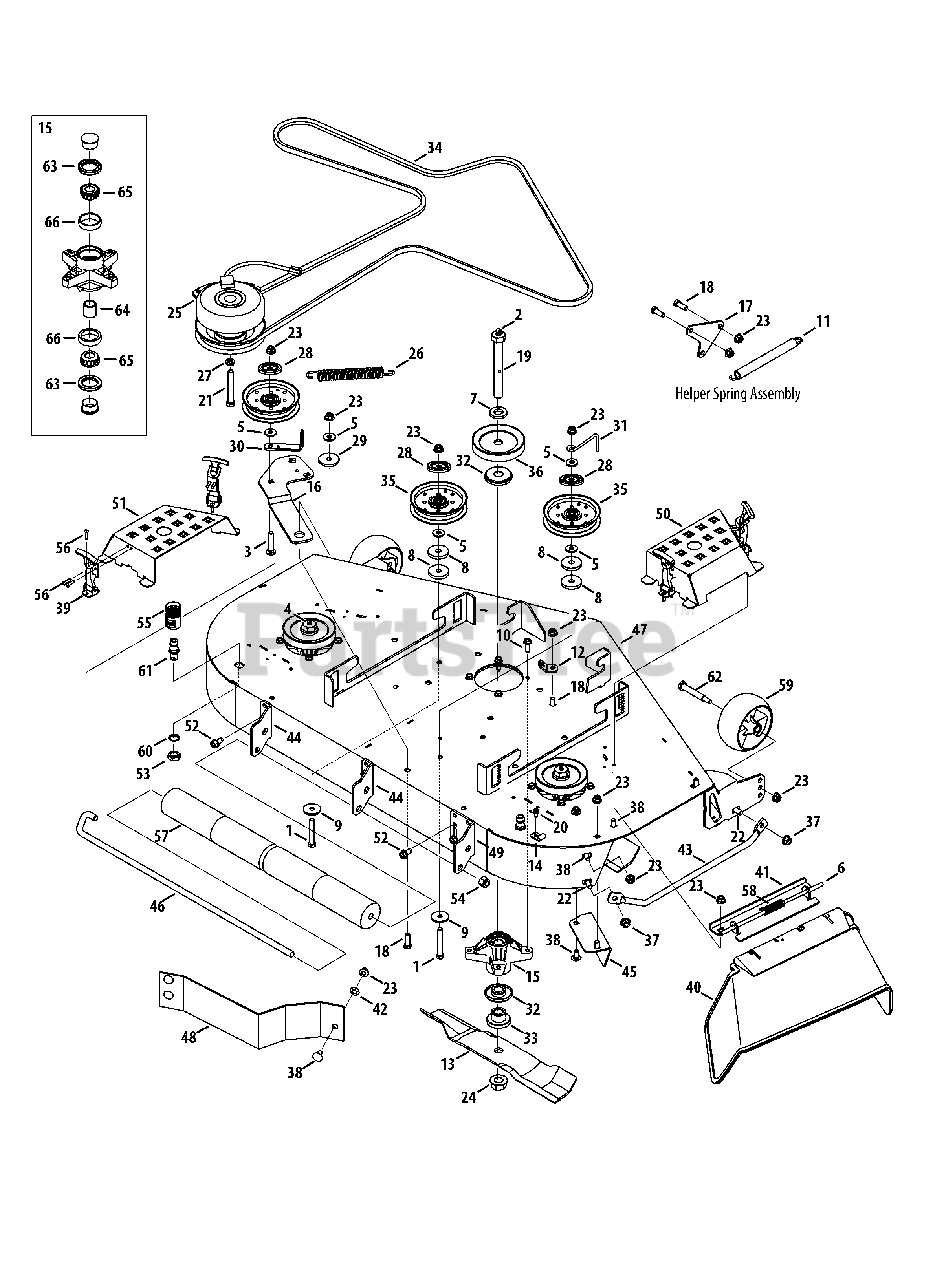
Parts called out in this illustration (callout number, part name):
1	Hex Screw, 3/8-16 x 2.50
2	Grease Fitting, 1/4-28 x .788
3	Carriage Bolt, 3/8-16 x 2.00
4	Straight Grease Fitting, 1/4-28
5	Washer, .406 x 1.00 x .105
6	Chute Deflector Rod
7	Spacer, .812 x 1.47 x .218
8	Washer, .470 x 1.50 x .225
9	Washer, .390 x 1.50 x .134
10	Flange Hex TT Screw, 5/16-18 x 1.00
11	Hook Ext. Spring, .75 x 7.89 x .14
12	45-Degree Spring Mount Bracket
13	Hi-Lift Blade, 17.0
14	Retainer Hook Bracket
15	Deck Spindle Assembly
16	48" Plate Idler
17	Spring Mount Plate
18	Hex Screw, 3/8-16 x 1.00
19	Hex Screw, 3/4-16 x 6.00
20	Hex Washer TT Screw, 1/4-20 x .500
21	Hex Screw, 7/16-20 x 3.25
22	Carriage Bolt, 3/8-16 x 1.00
23	Flange Lock Nut, 3/8-16
24	Flange Lock Nut, 3/4-16
25	Electric PTO Clutch
26	Extension Spring, .91 x 7.33
27	Lock Washer, 7/16
28	Pulley Cap
29	Shoulder Spacer, .884 x .190
30	Belt Guard Bracket
31	Belt Keeper Rod
32	Deck Spindle Spacer
33	Spindle Spacer, .76 x 2.0 x 1.1
34	Hi-Performance Belt
35	Idler Pulley
36	V-Type Pulley
37	Counterlock Flange Nut, 3/8-16
38	Carriage Bolt, 3/8-16 x .75
39	T-Handle Latch Draw
40	Fab Deck Deflector Chute
41	Deflector Chute Bracket
42	Push Retainer Nut
43	Fab Deck Chute Finger Guard
45	Micro Chute Baffle
46	J-Hook w/ Threaded Roller
47	48" Deck, Yellow
48	48" Standard Baffle
49	Deck Roller Mount Bracket
50	48" RH Belt Cover
51	48" LH Belt Cover
52	Screw TT, 3/8-16 x .75
53	Hex Nut, M16-1.5
54	Lock Nut, Nylon Insert, 1/2-13
55	Water Nozzle Adapter
56	Pop Rivet, .187 Dia.
57	Front Roller
58	Spring Torsion, 0.639 ID x 2.16 LG
59	Deck Wheel, 5.0
60	Lock Washer, 17 x 23.8 x 1.95
61	Water Deck Nozzle
62	Shoulder Bolt, 3/8-16 x .496 x 2.50
64	Spacer, .78 x 1.0
65	Cone Bearing
66	Cup Bearing
